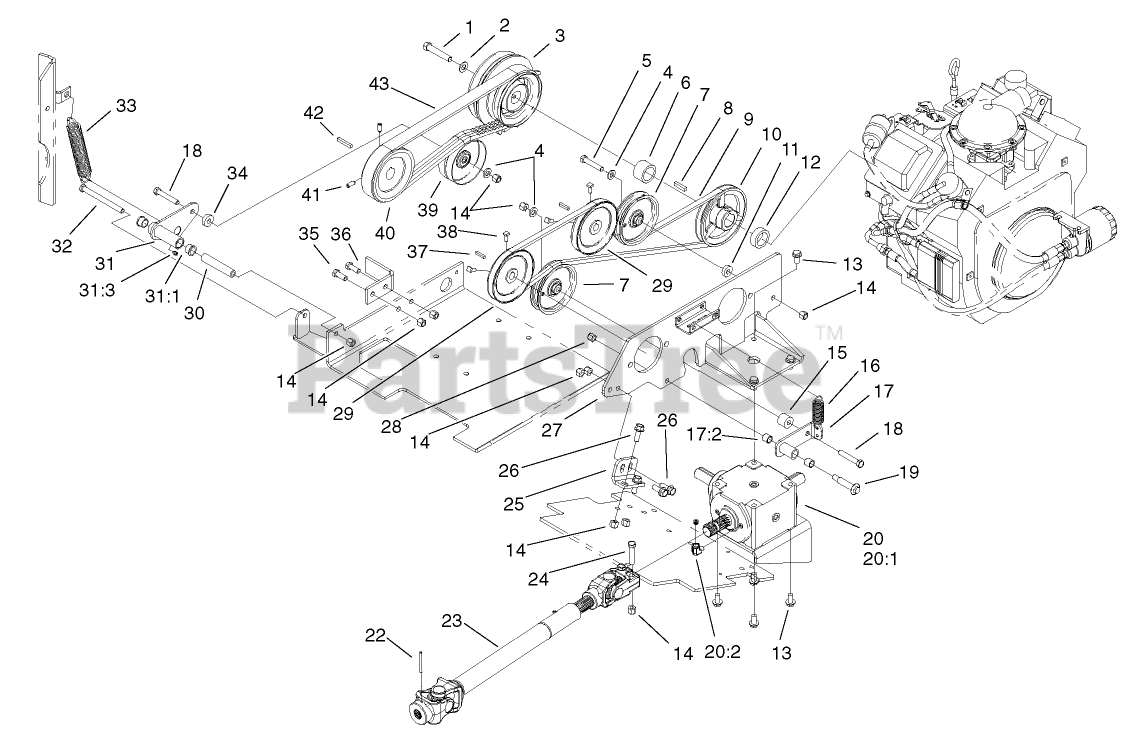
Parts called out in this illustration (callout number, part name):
1	SCREW-HH
2	WASHER-FLAT
3	CLUTCH
4	WASHER-FLAT
5	SCREW-HH
6	SPACER-SHAFT, ENGINE
7	PULLEY-IDLER
8	KEY-SQUARE
9	V-BELT
10	PULLEY-ENGINE
11	Washer
12	SPACER-SHAFT, ENGINE
13	SCREW-HHF
14	NUT-LOCK, NI
15	SPACER-ARM, IDLER
16	SPRING-EXTENSION
17	IDLER ARM ASM
17:2	BUSHING
18	SCREW-HH
19	BOLT-WHEEL
20	Gearbox ASM
20:1	Gearbox-T
20:2	ELBOW
22	PIN-SPRING
23	SHAFT-DRIVE
24	SCREW-HH
25	MOUNT-PLATE, PUMP
26	SCREW-HHF
27	PUMP MOUNT ASM
28	NUT-LOCK
29	PULLEY-PUMP, TRACTION
30	SPACER-IDLER
31	IDLER ARM ASM
31:1	BUSHING
31:3	FITTING-STRAIGHT
32	SCREW-HH
33	SPRING-EXTENSION
34	SPACER-IDLER
35	SCREW-HH
36	STOP-CLUTCH
37	KEY-PUMP
38	SCREW-SET
39	PULLEY-FLAT
40	PULLEY-CLUTCH
41	SCREW-SET, HSH
42	KEY-SQUARE
43	BELT-V, BANDED
